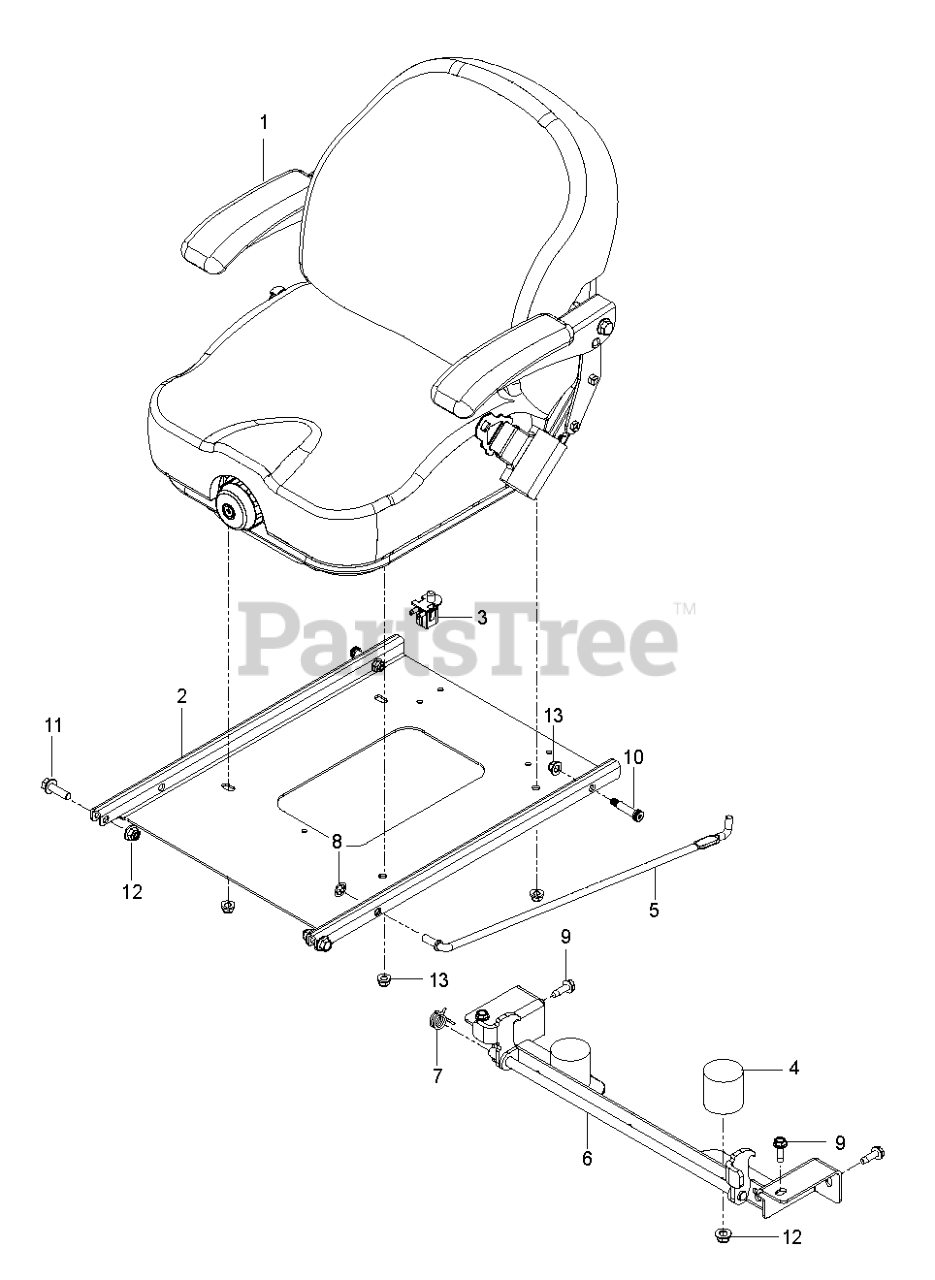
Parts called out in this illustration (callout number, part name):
1	SEAT C1110 EVC REDMAX W/ SEAT
2	PAN, SEAT, BLACK
3	SWITCH.SNAPMOUNT.NC
4	BUMPER, RUBBER
5	ROD, SEAT
6	BRACKET.PNT.LATCH.SEAT.BUMPER
7	SPRING, TORSION
8	NUT 3/8 PALNUT RTNG BLK PHOS
9	SCREW
10	BOLT, SHOULDER 3/8 X 1.25
11	HHFS 3/8-16 X 1.25 GD 5
12	NUT 3/8-16 HEX FLG NYLOC ZD
13	5/16-18 NYLOC FLANGE NUT
